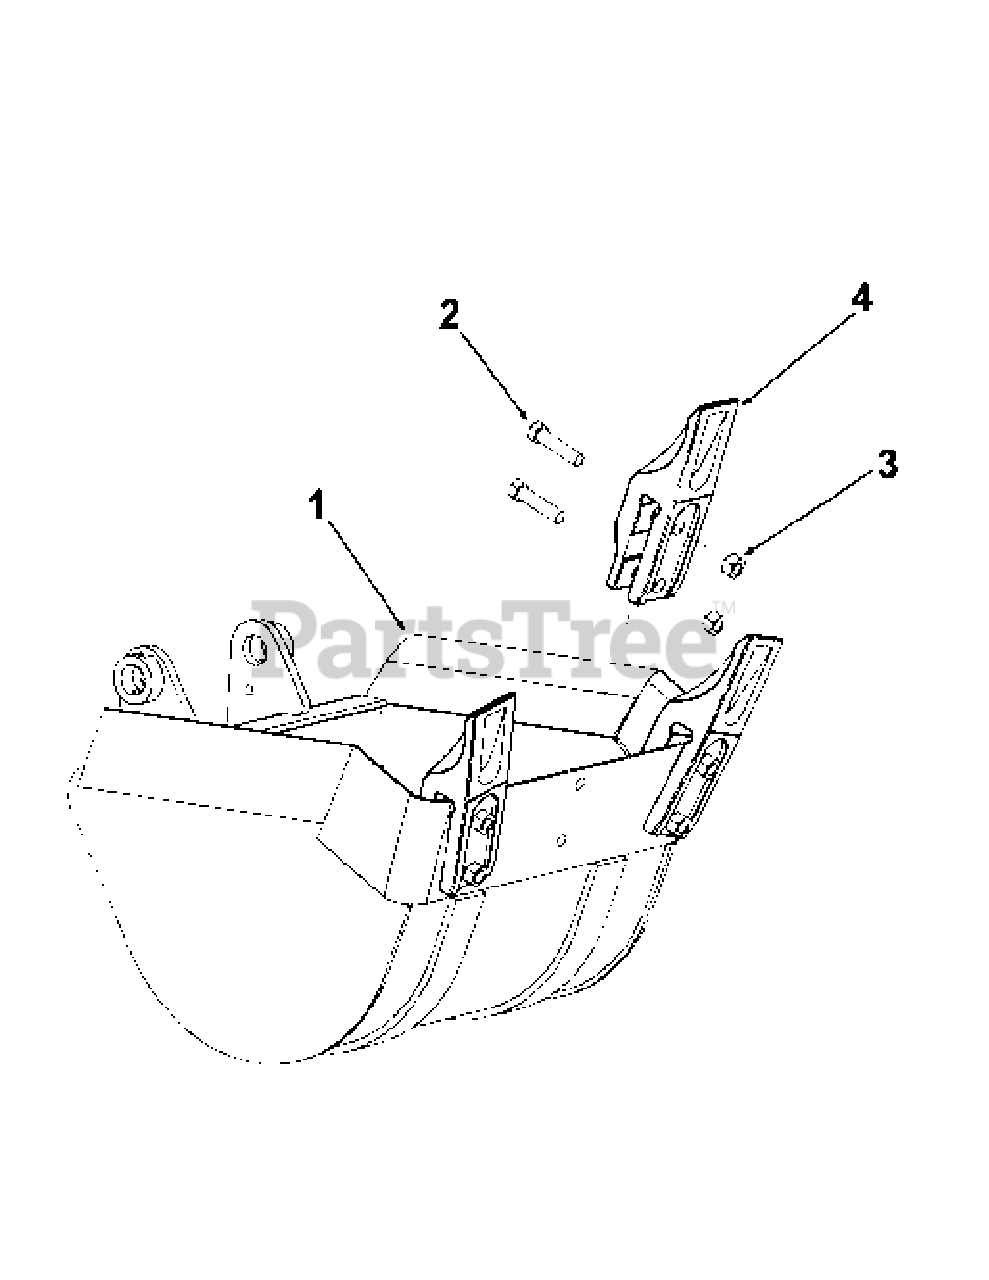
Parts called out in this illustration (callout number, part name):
1	Heavy Duty Bucket - 14"
1	Heavy Duty Bucket - 18"
1	Heavy Duty Bucket - 24"
1	Heavy Duty Bucket - 36"
2	Bolt, 1/2 NF x 1-3/4 Gr 5
3	Locknut, 1/2 NF
4	Tooth Point
